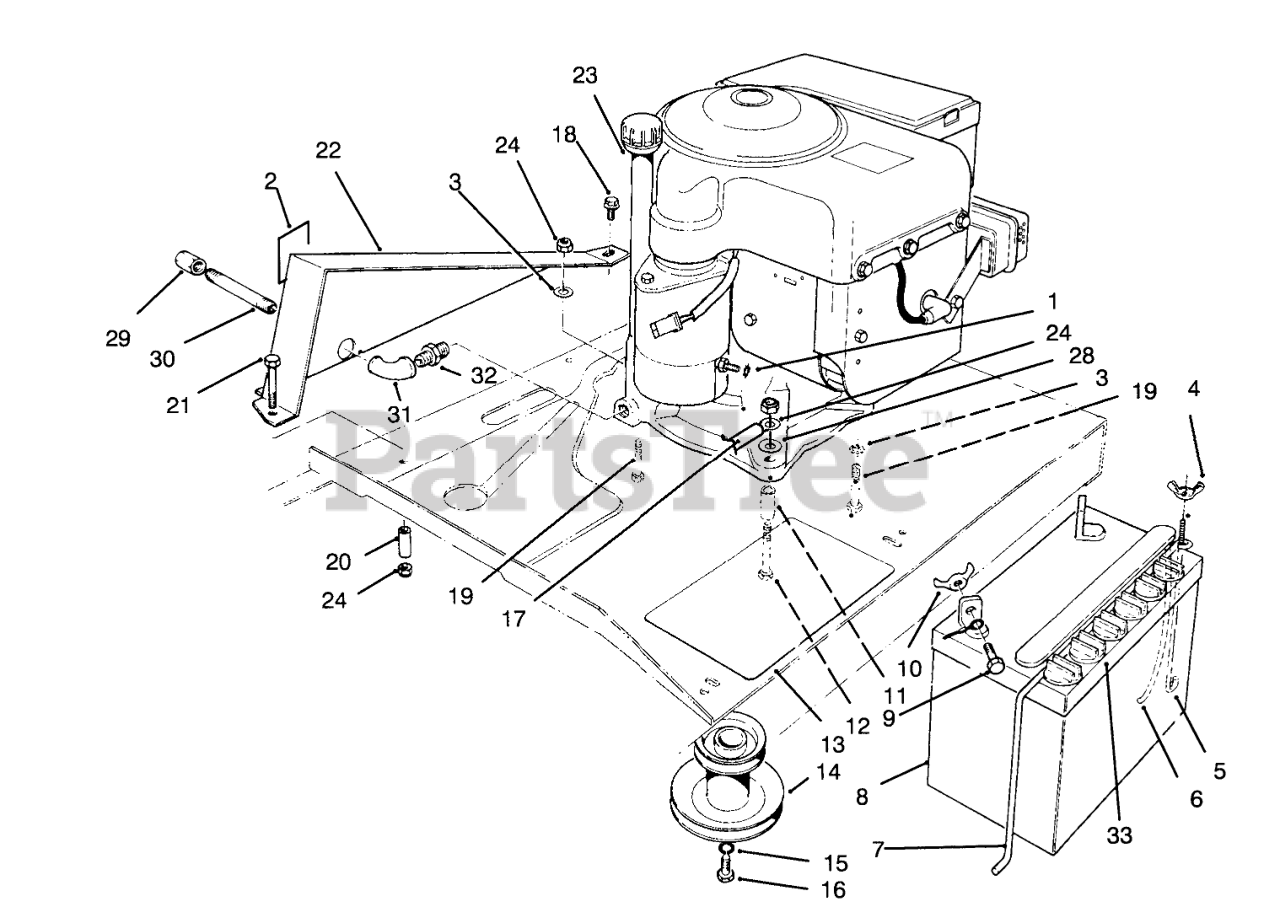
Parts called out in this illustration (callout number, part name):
1	WASHER-LOCK/EXT
3	WASHER-PLAIN
4	NUT-WING SPECL
5	POST-BATTERY
6	TUBE-BATT DRAIN/80-2600
7	HOLDDOWN-BATTERY
8	Battery
9	SCREW-HH
10	NUT-WING
11	SPACER-PIVOT
12	SCREW-HH
13	PAD-SKID, ANTI
14	Pulley-Engine
15	WASHER-FLAT
16	SCREW-HH
17	WIRE ASM
18	SCREW-HWHTF
19	SCREW-HH
20	GUIDE-BELT
21	SCREW-HH
22	GUIDE-CHAIN
23	Engine-8 H.P. B & S
24	NUT-LOCK, NI
28	WASHER-LOCK
29	CAP-PIPE
30	NIPPLE-PIPE
31	ELBOW-STREET
32	BUSHING-PIPE
33	BATTERY CAP
